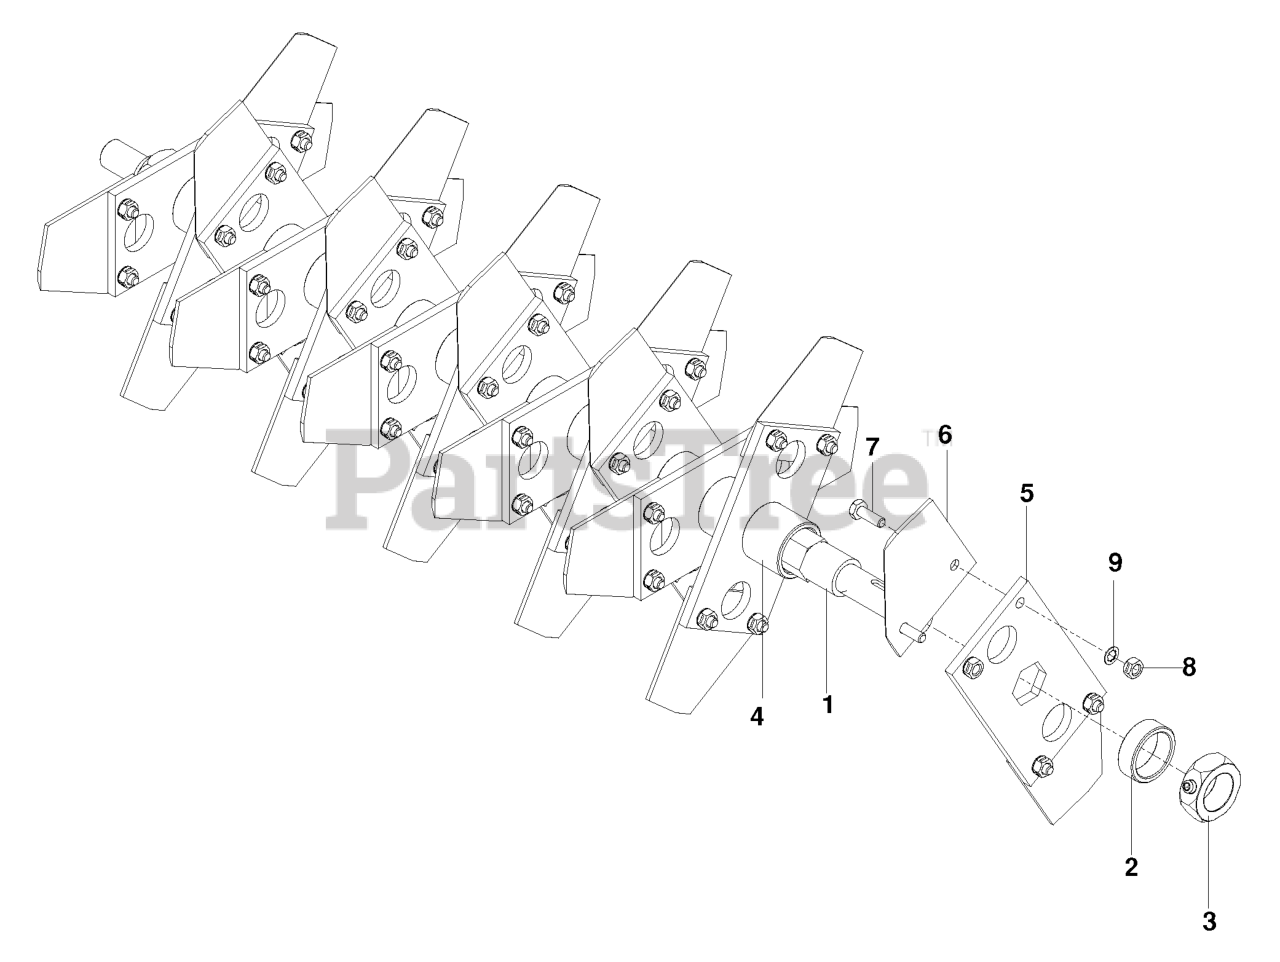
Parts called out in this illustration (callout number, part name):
2	END SPACER
3	JAM NUT W/SET SCREW
4	SPACER - LONG
5	BLADE MOUNTING PLATE
6	DELTA BLADE
7	HEX SCREW 1/4X.75
8	NUT 1/4C CENTER LOCK
9	TH CABLE AR# 441L-632-10
